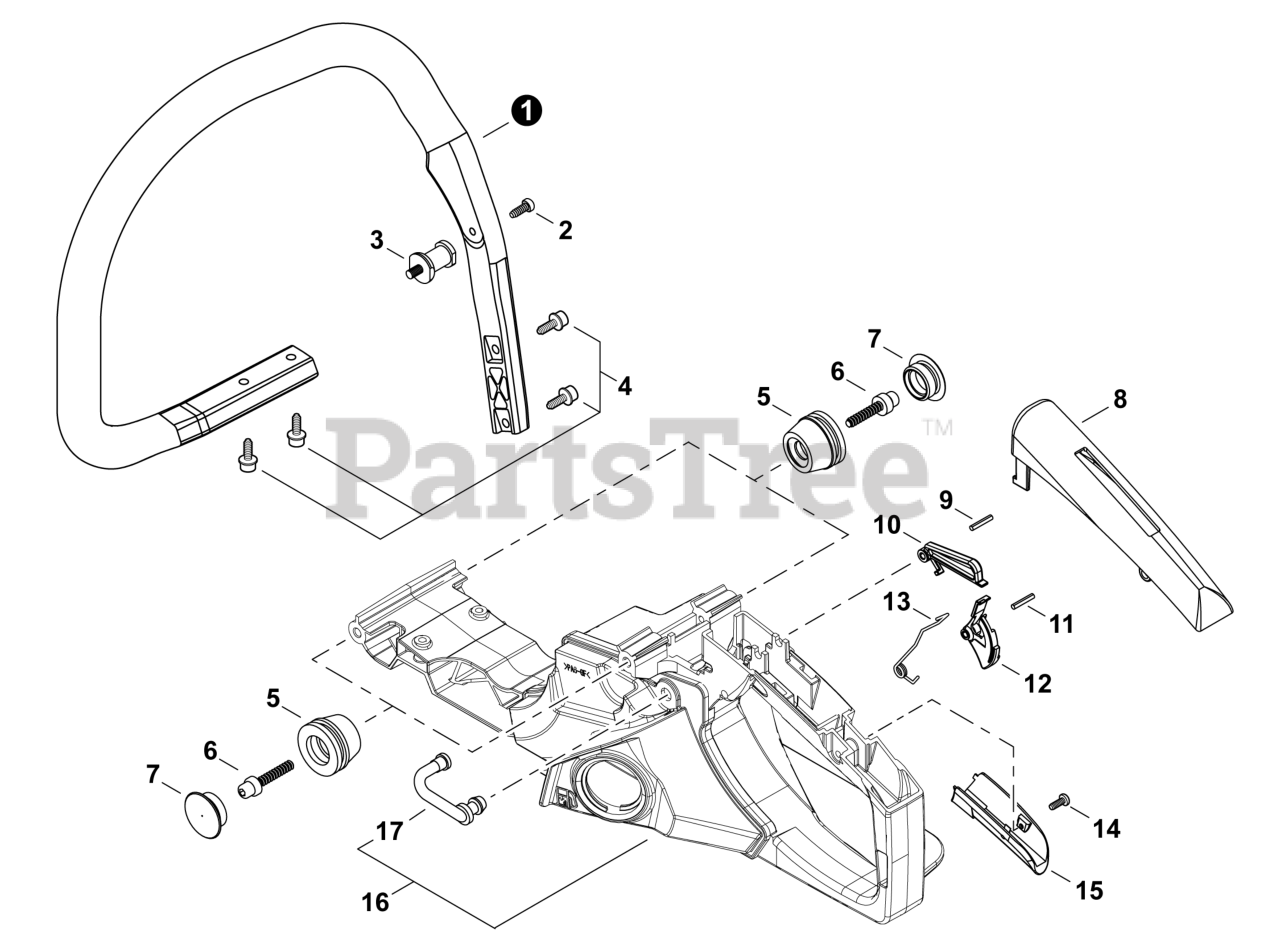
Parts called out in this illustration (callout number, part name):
1	HANDLE, FRONT
2	BOLT M4×14
3	CUSHION 5
4	BOLT 5×20
5	CUSHION
7	CAP, CUSHION
8	COVER, HANDLE
9	PIN, SPRING Ø4×22 MM
10	LOCKOUT, THROTTLE
11	PIN, SPRING Ø4×25 MM
12	TRIGGER, THROTTLE
13	SPRING, THROTTLE RETURN
14	SCREW 4×25
15	GRIP, HANDLE
16	HANDLE ASSY, REAR
17	PIPE, FUEL VENT, CS-490/501
